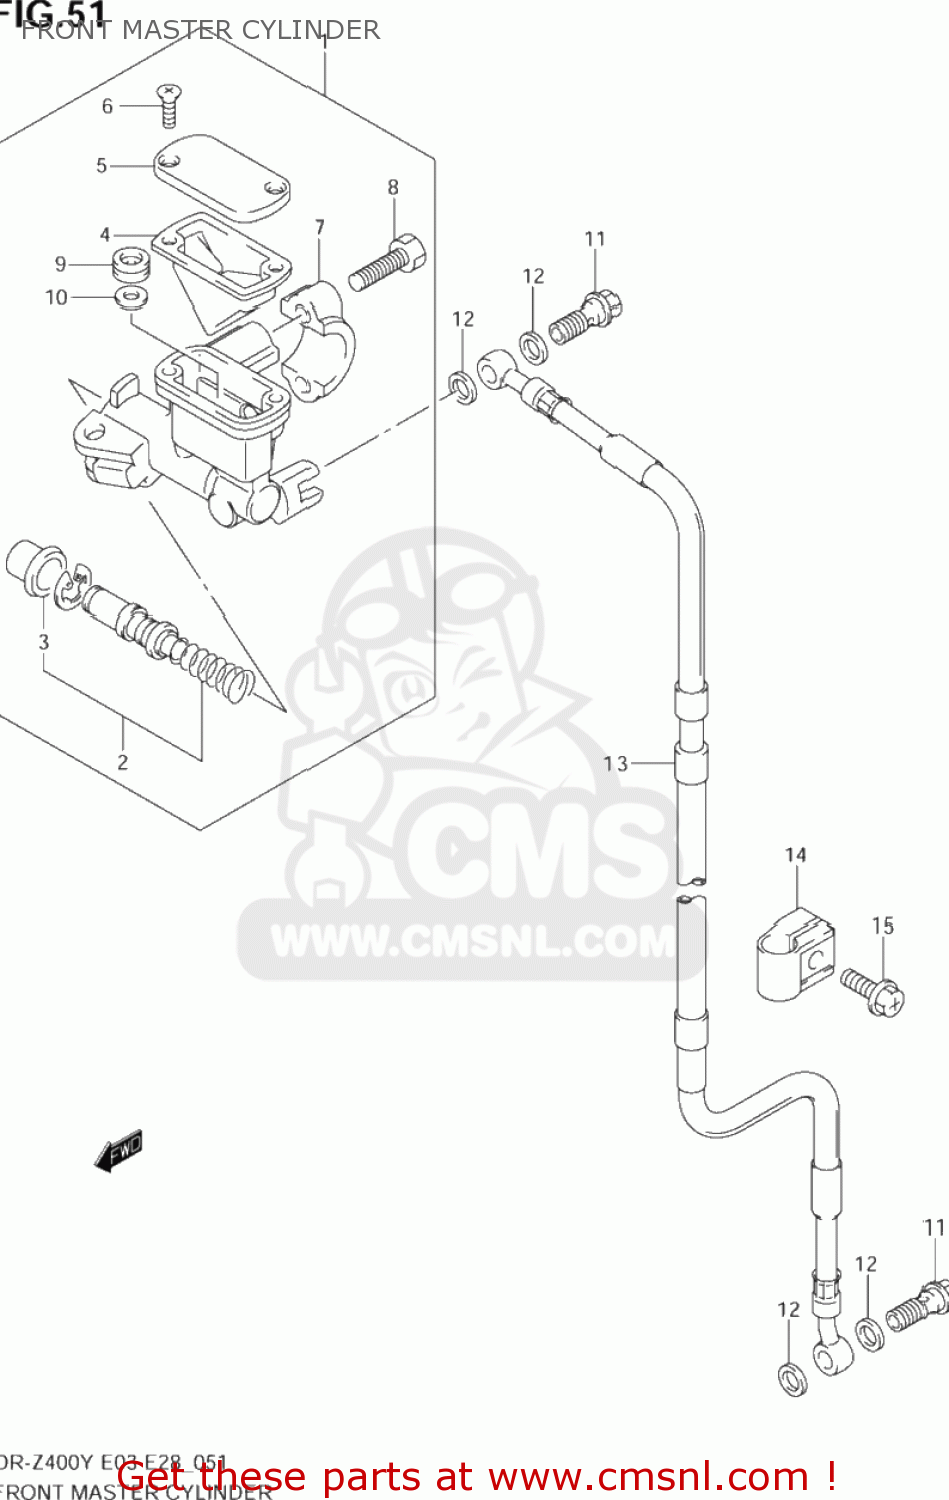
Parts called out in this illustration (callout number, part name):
1	CYLINDER ASSY,FR MASTER
2	PISTON & CUP SET
3	BOOT
4	DIAPHRAGM
5	CAP
6	SCREW
7	HOLDER
8	BOLT
9	SEPARATOR
10	RING
11	BOLT UNION
12	WASHER(10X15X1.5)
13	HOSE COMP,FRONT BRAKE
14	CLAMP,FR BRAKE
15	SCREW
